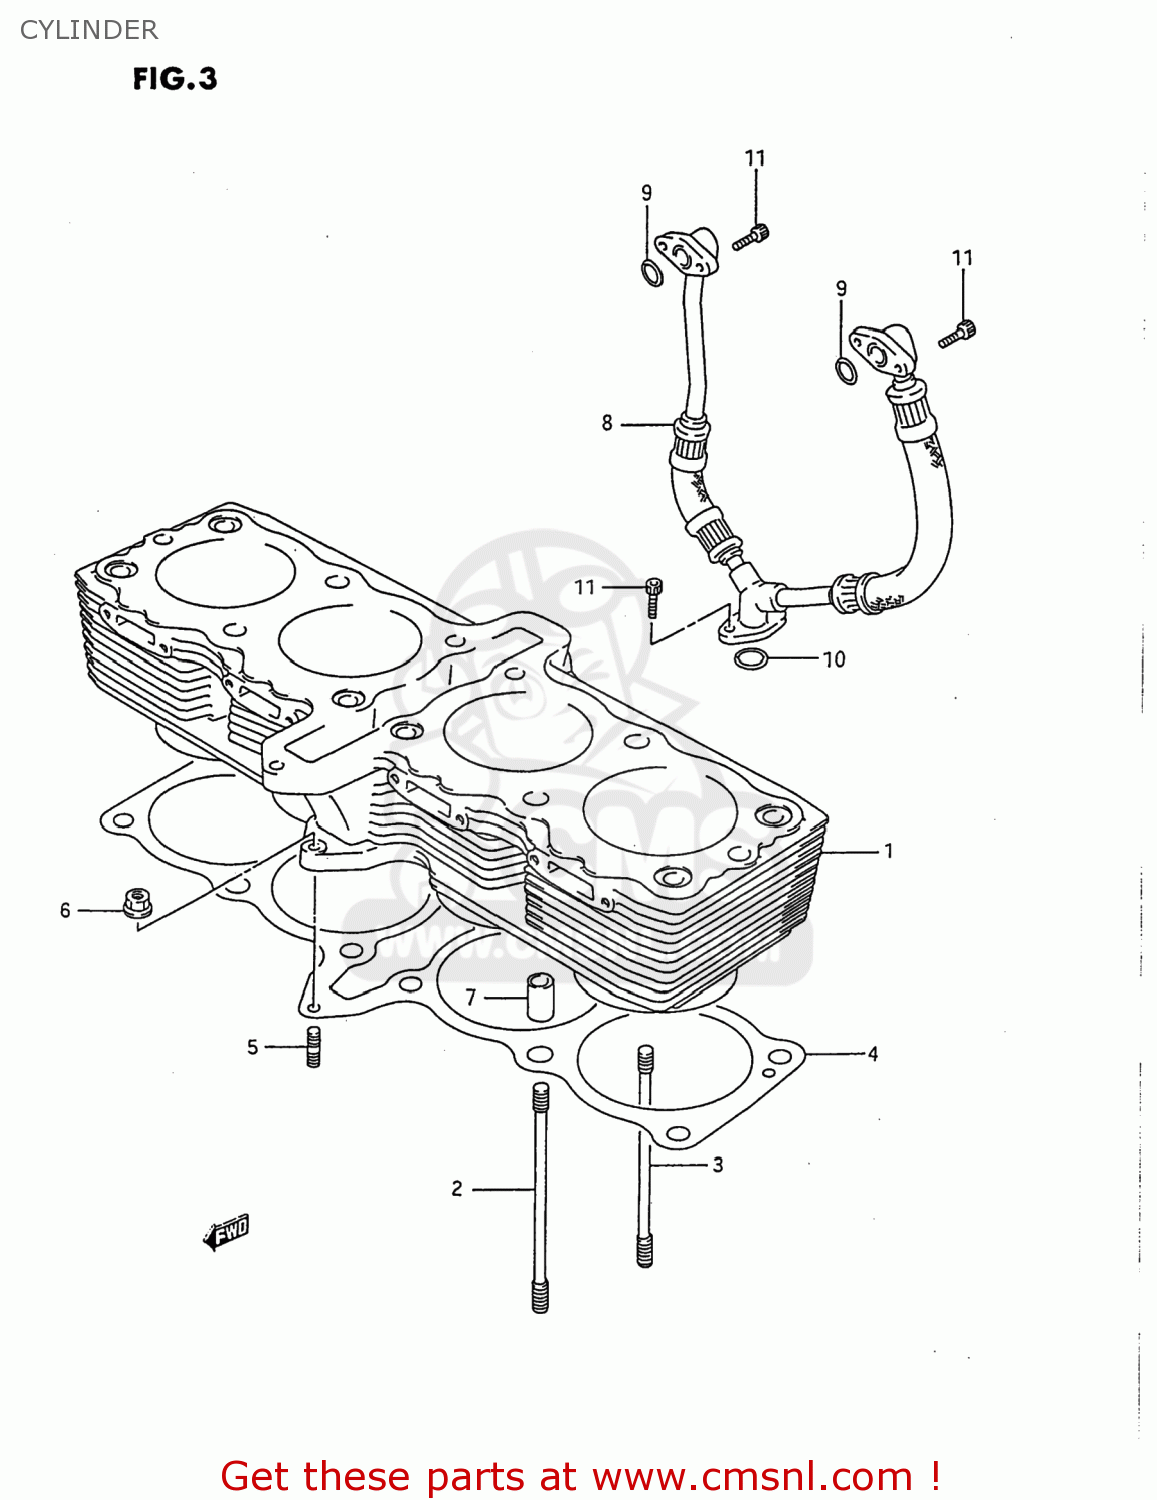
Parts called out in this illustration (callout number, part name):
1	CYLINDER
2	BOLT,STUD
3	BOLT,STUD
4	GASKET,CYLINDER (NAS)
5	STUD,M6X1X32
6	NUT
7	PIN(13X10.4X20)
8	HOSE,OIL HEAD COOLER
9	O RING(D:2.5,ID:13.8)
10	O RING(D:2.4,ID:15.8)
11	BOLT,OIL FILLE
